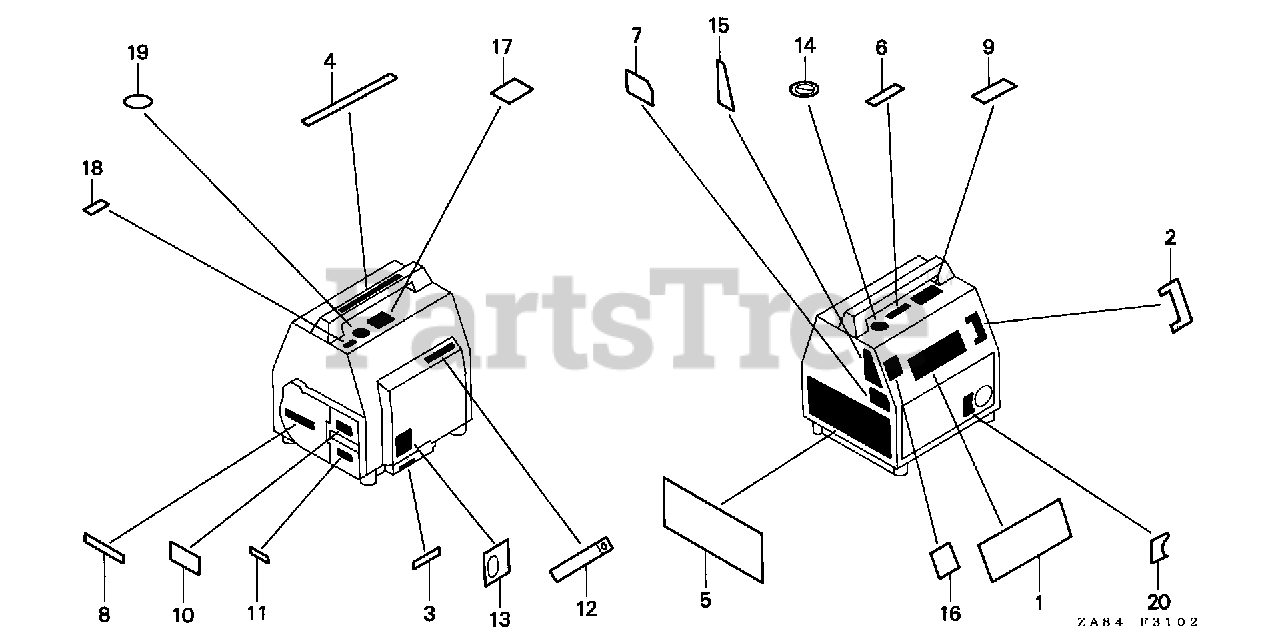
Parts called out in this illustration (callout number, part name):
1	MARK, EMBLEM
2	MARK, ENGINE SWITCH
3	MARK, TOOL
4	MARK, SCALE
5	MARK, CAUTION
6	LABEL, RAIN WARNING (ENGLISH)
7	MARK, D.C. CAUTION
8	MARK, HONDA
9	MARK, OIL ALERT (E)
10	MARK, AIR CLEANER CAUTION
11	MARK, OPEN
12	MARK, EX. CAUTION
13	MARK, FREQUENCY POSITION
14	LABEL, CONNECT WARNING (ENGLISH)
15	MARK, A.C. CAUTION
16	MARK, CIRCUIT BREAKER
17	MARK, FUEL CAUTION
18	LABEL, FIRE CAUTION
19	LABEL, FUEL CAUTION
20	MARK, OIL CAUTION
